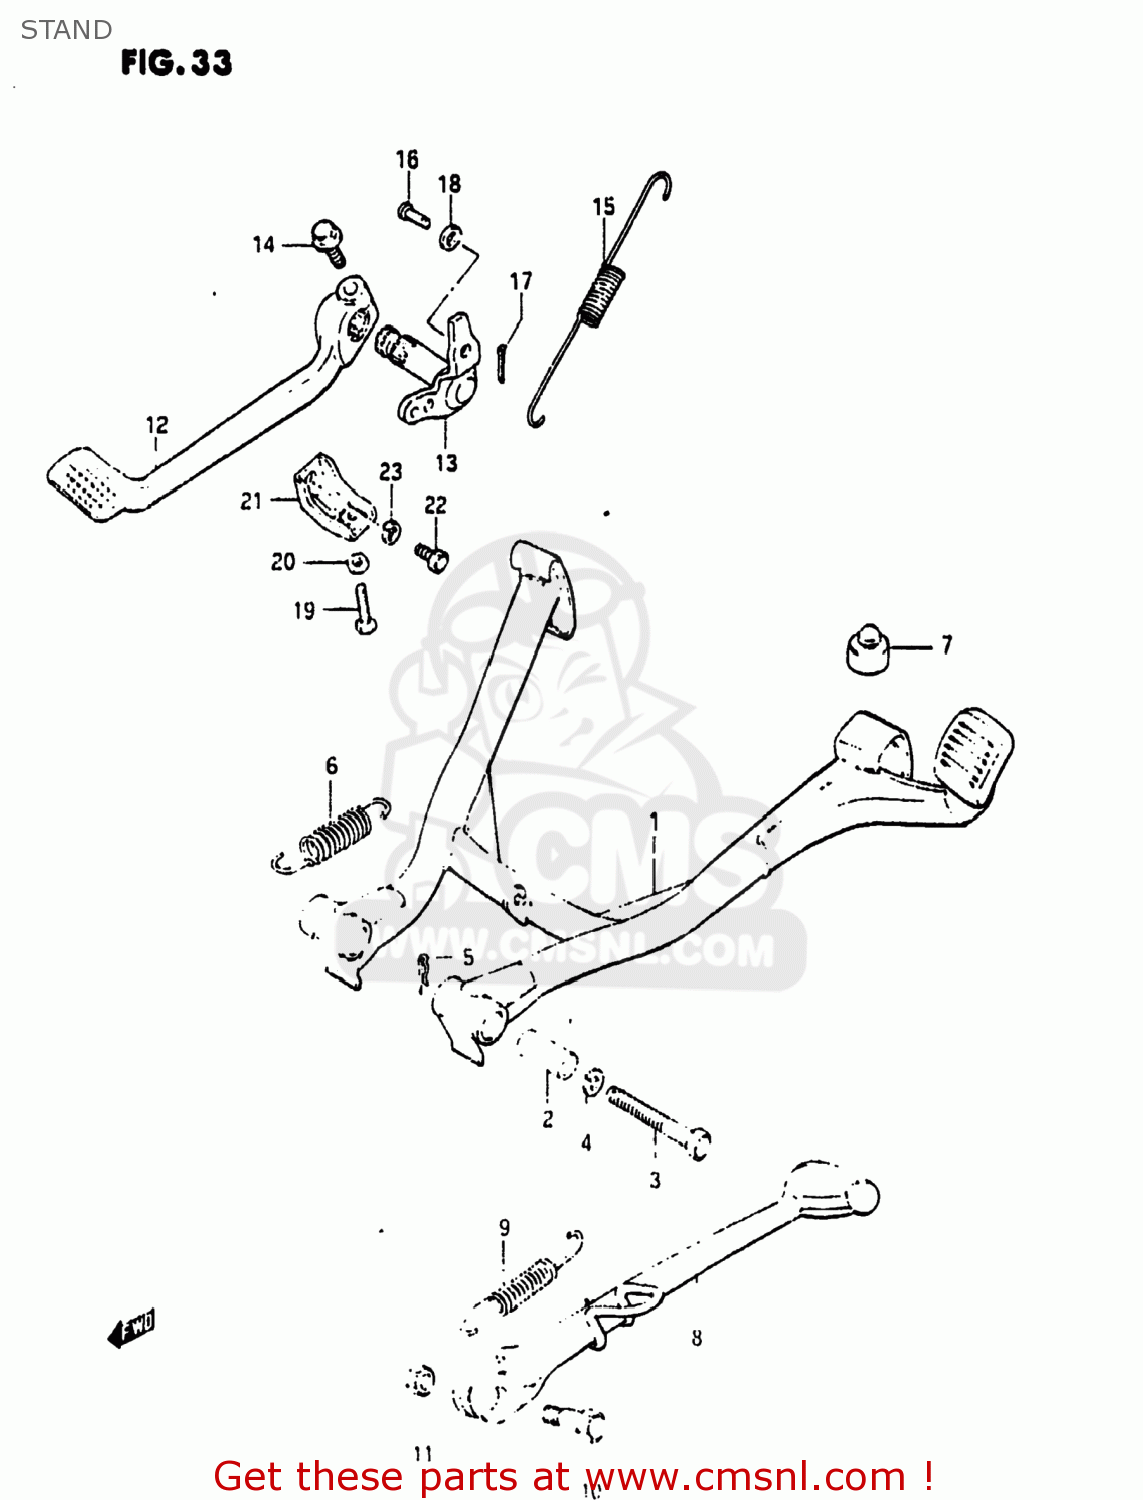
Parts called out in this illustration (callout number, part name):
1	STAND,CENTER
2	SPACER(10X16X38.8)
3	BOLT
4	WASHER,LOCK,10
5	CLIP
6	SPRING
7	CUSHION(11.5X22X20)
8	STAND,SIDE
9	SPRING
10	BOLT(10X32)
11	NUTM10X1.25X8
12	PEDAL,BRAKE
13	ARM,BRAKE PEDAL ROD
14	BOLT
15	SPRING
16	PIN
17	PIN
18	WASHER
19	BOLT(6X25)
20	NUT 6MM
21	BRACKET, BRAKE ADJUSTE
22	BOLT
23	WASHER,LOCK
